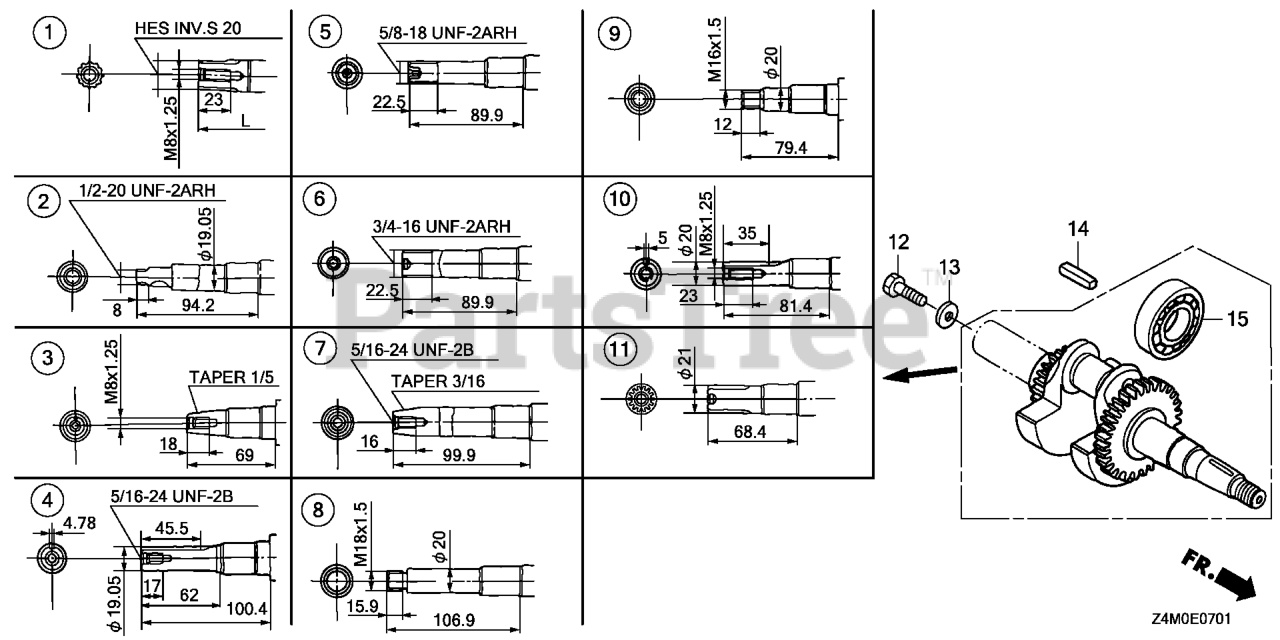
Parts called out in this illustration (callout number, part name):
7	CRANKSHAFT
15	BEARING, RADIAL BALL (6205)
15	BEARING, RADIAL BALL (6205) (NSK)
